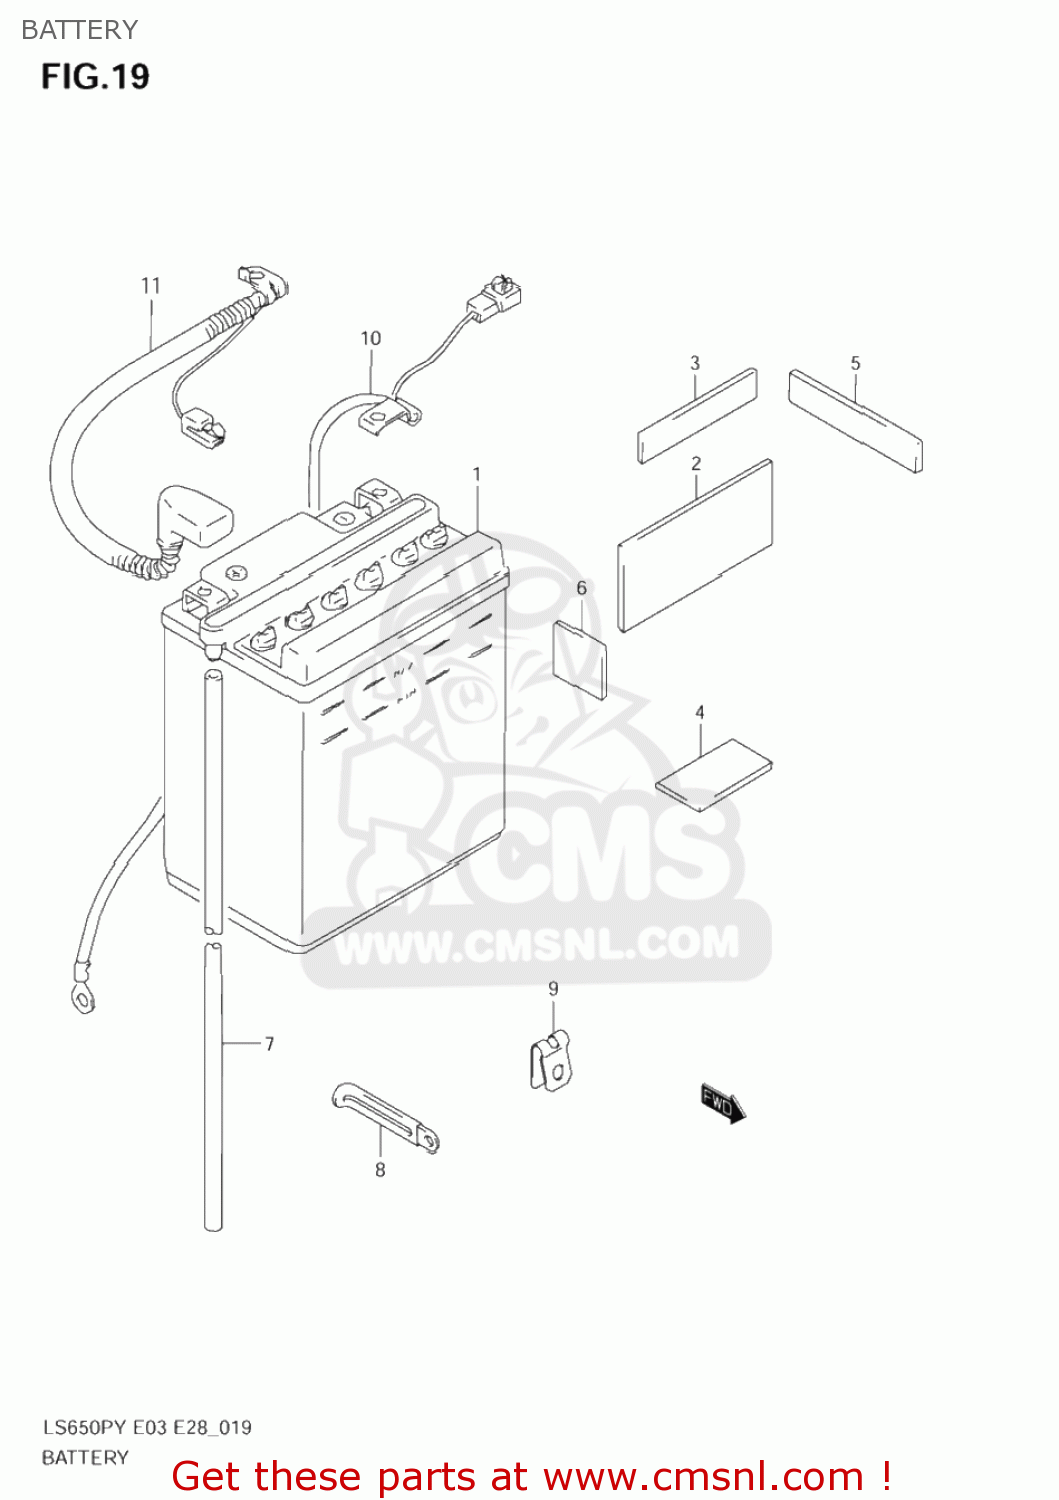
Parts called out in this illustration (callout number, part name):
1	BATTERY(YB14L-B2,12V14.7AH)
2	PROTECTOR(170X95X3.0)
3	PROTECTOR(170X95X3.0)
4	PROTECTOR(170X95X3.0)
5	PROTECTOR(80X80X2)
6	PROTECTOR(50X50X5)
7	HOSE,BATTERY EXHAUST(L:780)
8	CLAMP(L:45)
9	CLAMP
10	WIRE,BATTERY MINUS
11	WIRE,BATTERY PLUS LEAD
